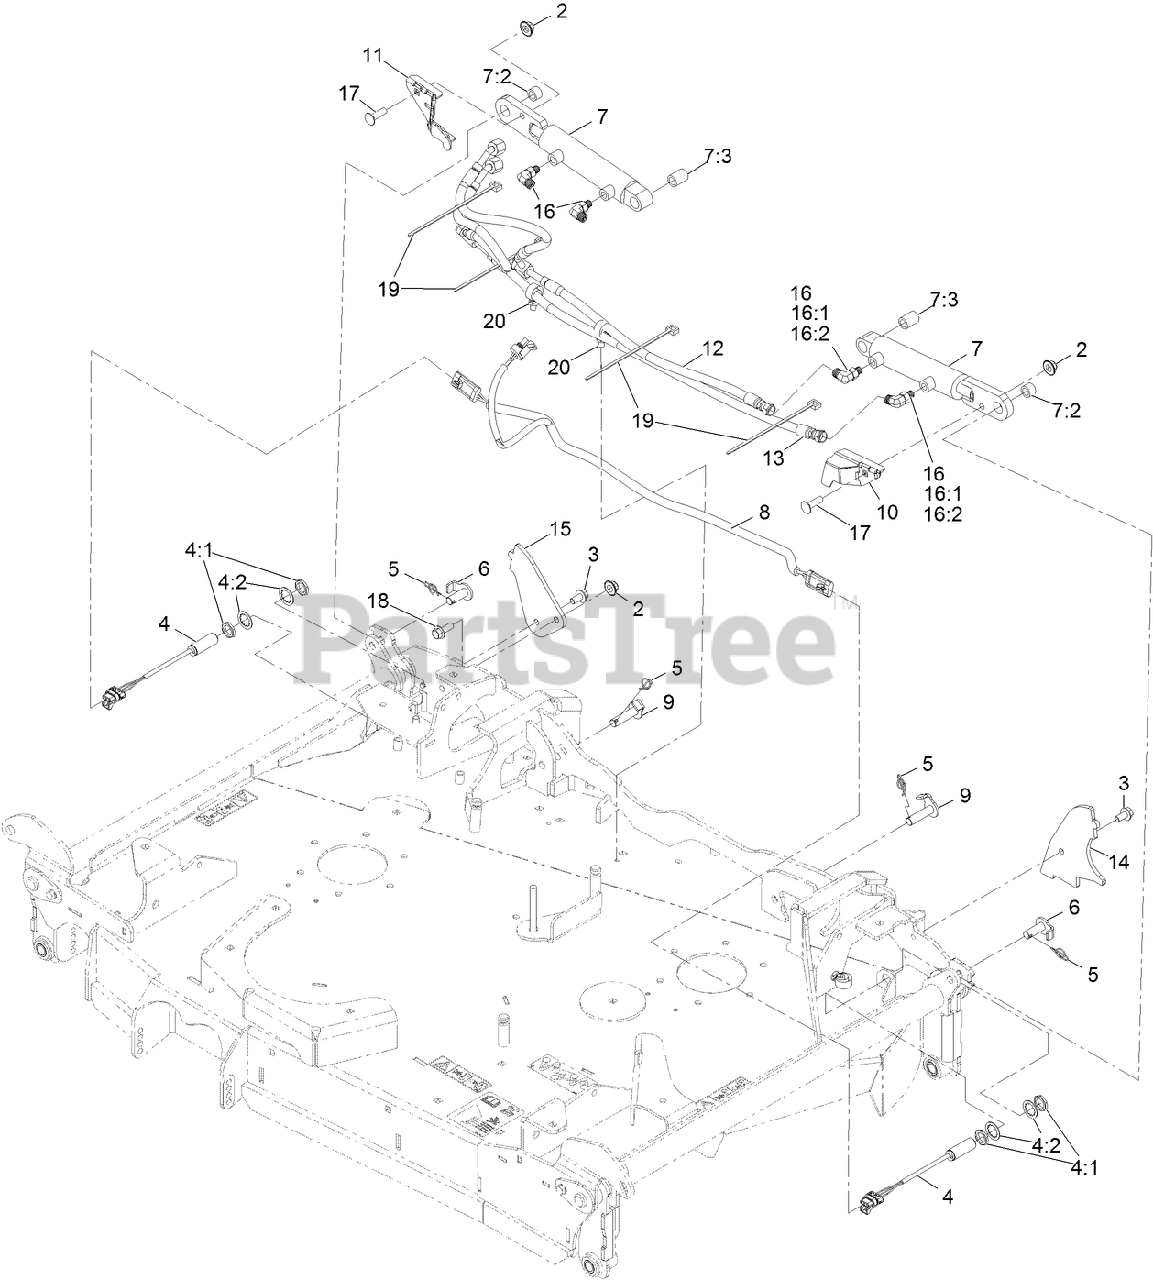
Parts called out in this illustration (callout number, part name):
2	NUT-FLANGE, NI
3	SCREW-HWH
4	PROXIMITY SWITCH ASM
4:1	NUT-HEX
4:2	WASHER-LOCK, INTERNAL TOOTH
5	PIN-COTTER, LOCKING
6	EYE-PIN, CYLINDER
7	DECK FOLD CYLINDER ASM
7:2	BUSHING
7:3	BUSHING
8	HARNESS-WIRE
9	BASE-PIN, CYLINDER
10	ASM-PROX TARGET, LH
11	ASM-PROX TARGET, RH
12	HOSE ASM
13	HOSE ASM
14	BRACKET-DECK STOP, LH
15	BRACKET-DECK STOP, RH
16	FITTING-ELBOW, 90 DEG
16:1	O-RING
16:2	O-RING
17	SCREW-CARR
18	SCREW-HHF
19	TIE-CABLE
20	CLIP-TIE
